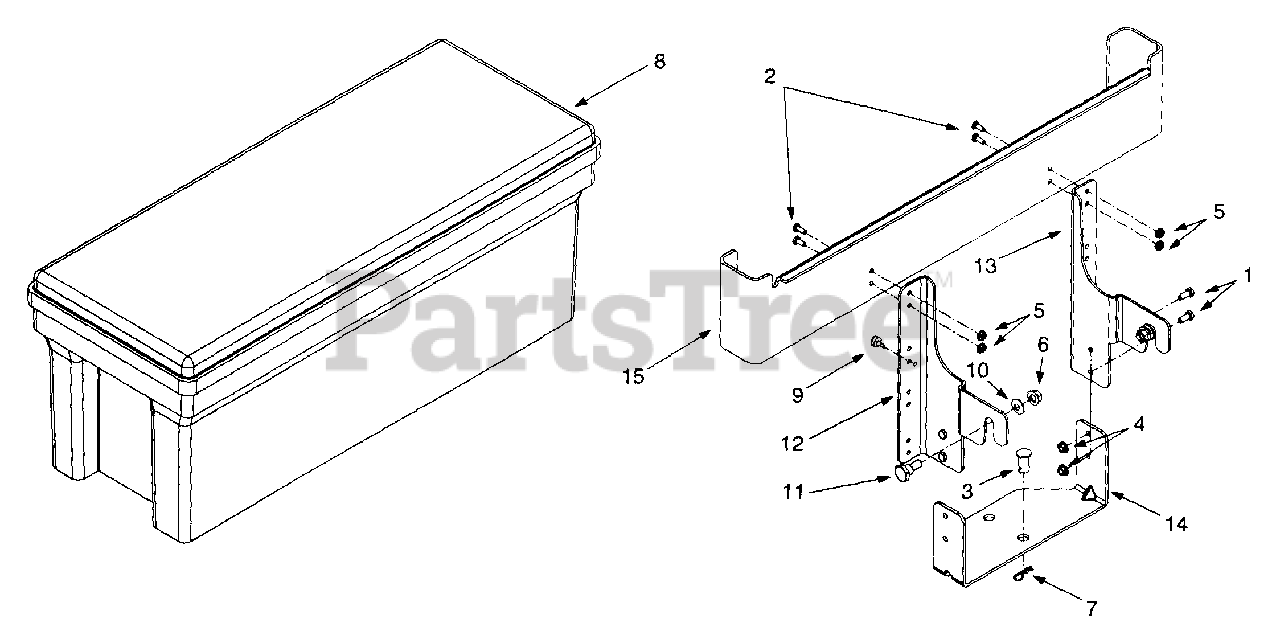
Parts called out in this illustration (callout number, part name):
1	Hex Cap Screw, 5/16-18 x .75
2	Hex Cap Screw, 1/4-20 x .62
3	Clevis Pin
4	Hex Flange Lock Nut, 5/16-18
5	Hex Flange Lock Nut, 1/4-20
6	Hex Flange Lock Nut, 7/16-20
7	Internal Cotter Pin, .148 x 3
8	Plastic Tool Box
9	Bumper, .62 Dia. x .3
10	Bell Washer, .45 x 1.0 x .062
11	Shoulder Screw, .625 x .5, 7/16-20
12	RH Support Bracket
13	LH Support Bracket
